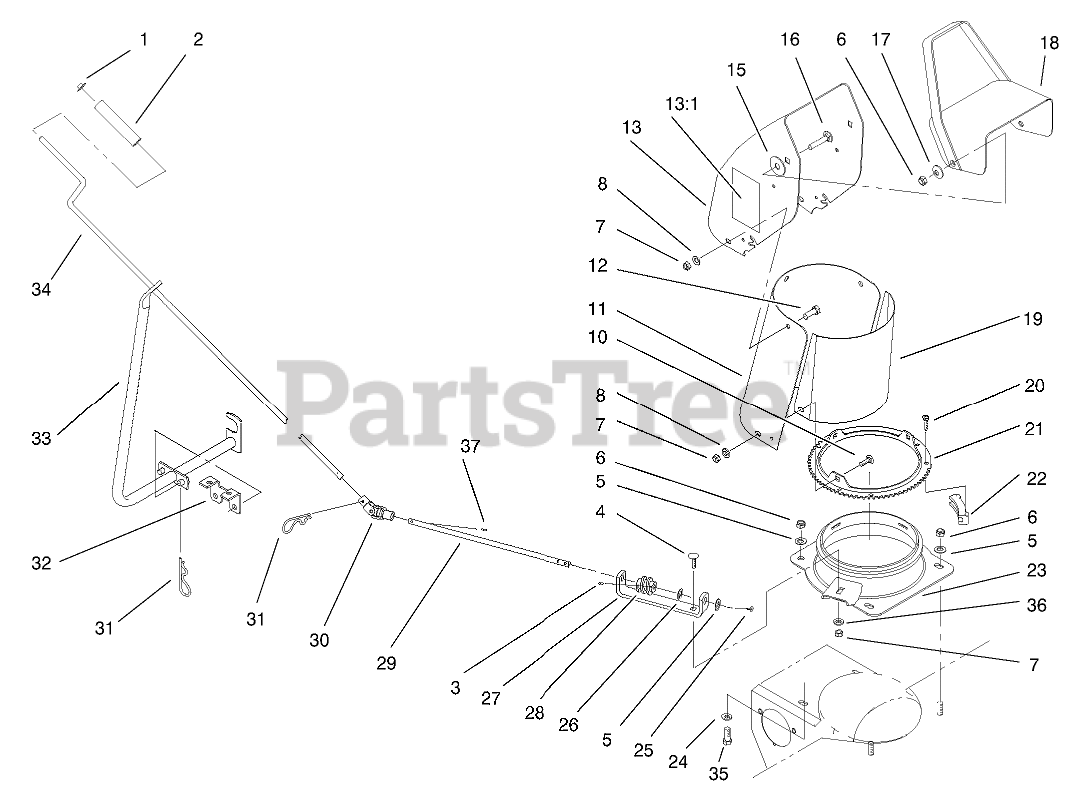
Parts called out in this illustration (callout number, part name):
1	RETAINER-PUSH ON
2	GRIP-CONTROL, CHUTE
3	PIN-SPRING
4	BOLT-CARR
5	WASHER-FLAT
6	NUT-LOCK, NI
7	NUT-LOCK, NI
8	WASHER-PLAIN
10	BOLT-CARR
11	EXTENDER-CHUTE, UPPER
12	SCREW-HH
13	CHUTE
13:1	DECAL-DISCHARGE DANGER
15	WASHER-RUBBER
16	BOLT-CARR
17	WASHER-BELLEVILLE
18	DEFLECTOR
19	SHIELD-DEFLECTOR
20	SCREW-SPECIAL
21	CHUTE SWIVEL RING
22	RETAINER-CHUTE
23	ADAPTER
24	WASHER-SPACER
25	PIN-COTTER
26	WASHER-SPRING
27	BRACKET-WORM
28	GEAR-WORM, CHUTE
30	JOINT-UNIVERSAL
31	PIN-HAIR
32	BRACKET
33	SUPPORT
34	ROD-CHUTE CONTROL
35	SCREW-HH
36	WASHER-LOCK
37	PIN-SPRING
